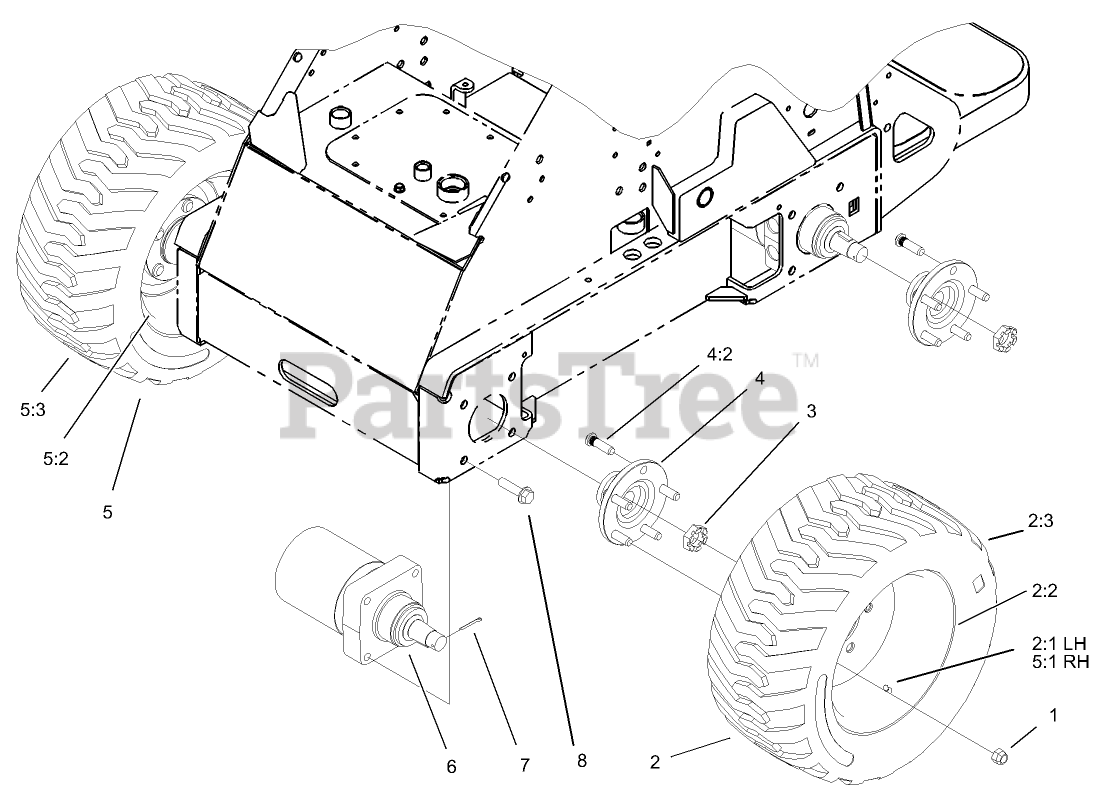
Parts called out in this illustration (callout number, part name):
1	NUT-LUG
2	LH WHEEL AND TIRE ASM
2:1	STEM-VALVE
2:2	WHEEL
4	HUB ASM
4:2	STUD-TYPE, DRIVE
5	RH WHEEL AND TIRE ASM
5:1	STEM-VALVE
5:2	WHEEL
6	HYD MOTOR ASM
7	PIN-COTTER
8	SCREW-HHF
